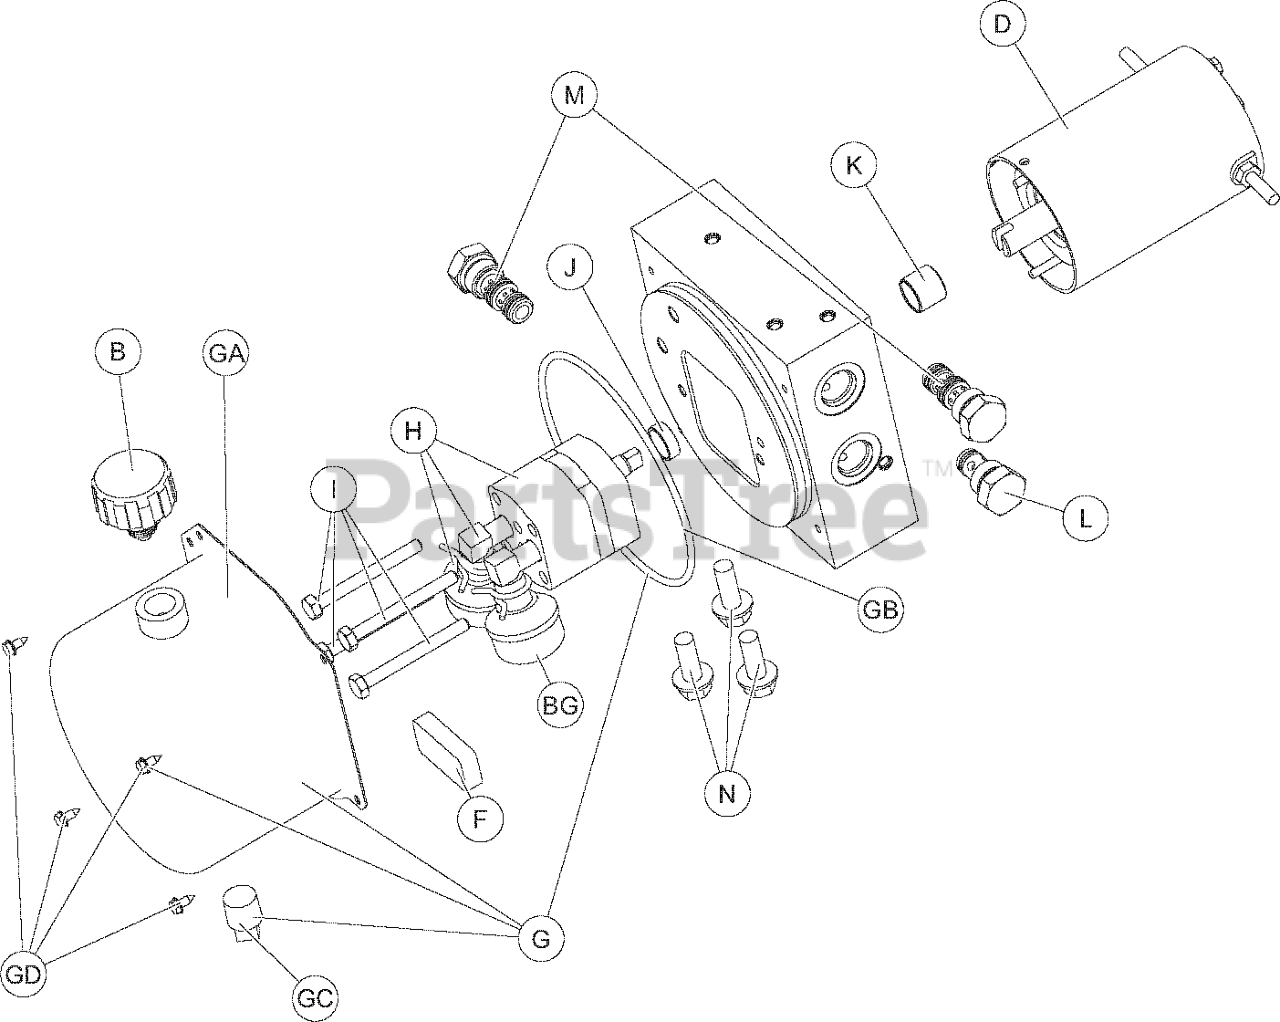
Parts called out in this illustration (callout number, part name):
B	BREATHER, PRESSURE CONTROL
D	ASM, MOTOR 3"
G	KIT, RESERVOIR
H	KIT, BIDIRECTIONAL PUMP
I	HHCS 1/4-20 X 2-1/2 G5
J	PUMP, SHAFT SEAL
K	BRG, SLV
L	CHECK VALVE, CV08-20
M	VALVE, PC08-30 W/NUT
N	HHCS, FLG 3/8 X 1 SERRATED (QTY 3)
GB	O-RING, 2-251
GC	PLUG, SQUARE 3/8 NPTF
GD	HARDWARE, RESERVOIR
GA	RESERVOIR
BG	SCREEN, BI-DIRECTIONAL PUMP (QTY 2)
